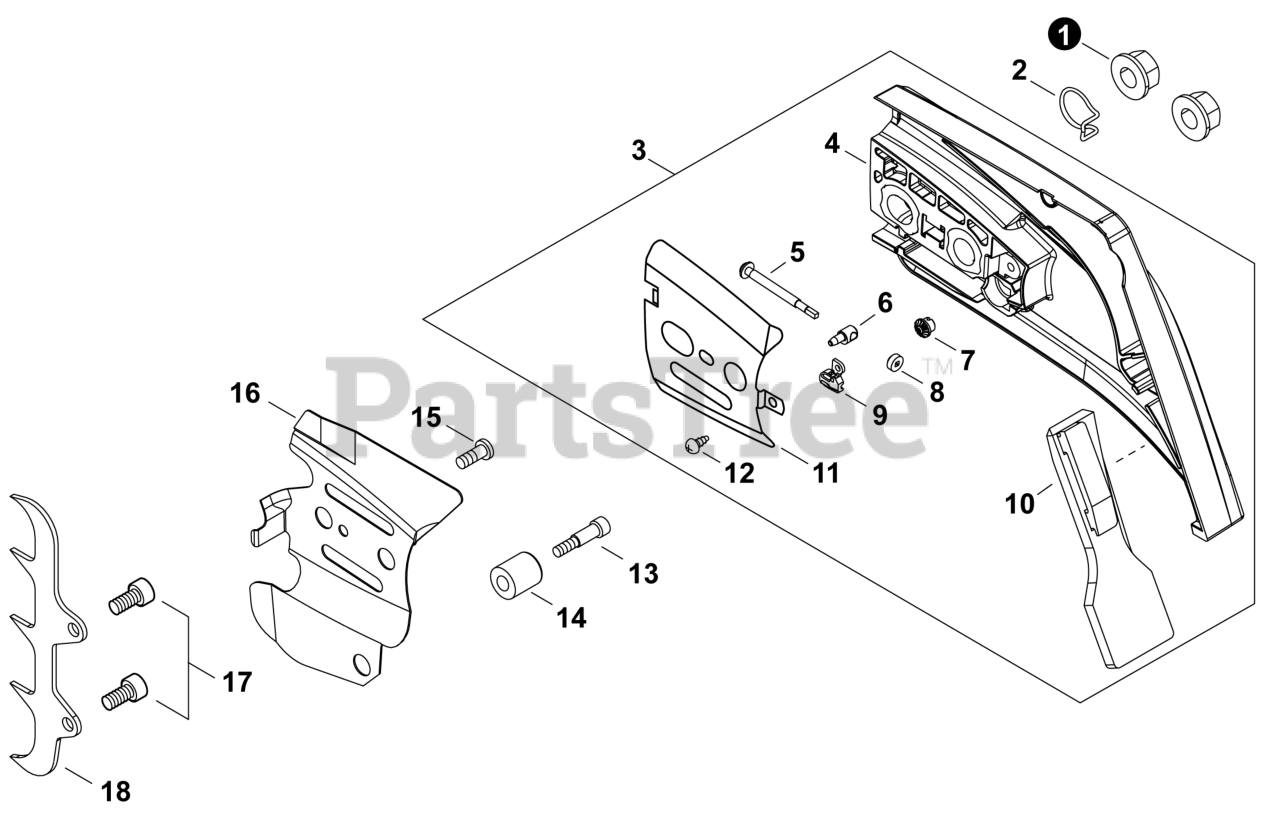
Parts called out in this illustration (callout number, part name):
3	COVER ASSY, CLUTCH
4	GUARD, SPROCKET
5	SCREW, CHAIN TENSION
6	TENSIONER, CHAIN
7	GEAR, BEVEL
8	GEAR, BEVEL
9	COLLAR 8
10	PROTECTOR
11	PLATE, GUIDE - OUTER
12	SCREW 4×8
14	CHAIN CATCHER
15	SCREW M4×7
16	PLATE, GUIDE - INNER
17	BOLT 5×12
18	SPIKE, BUMPER
19	BOLT 5×12
20	SPIKE, BUMPER
